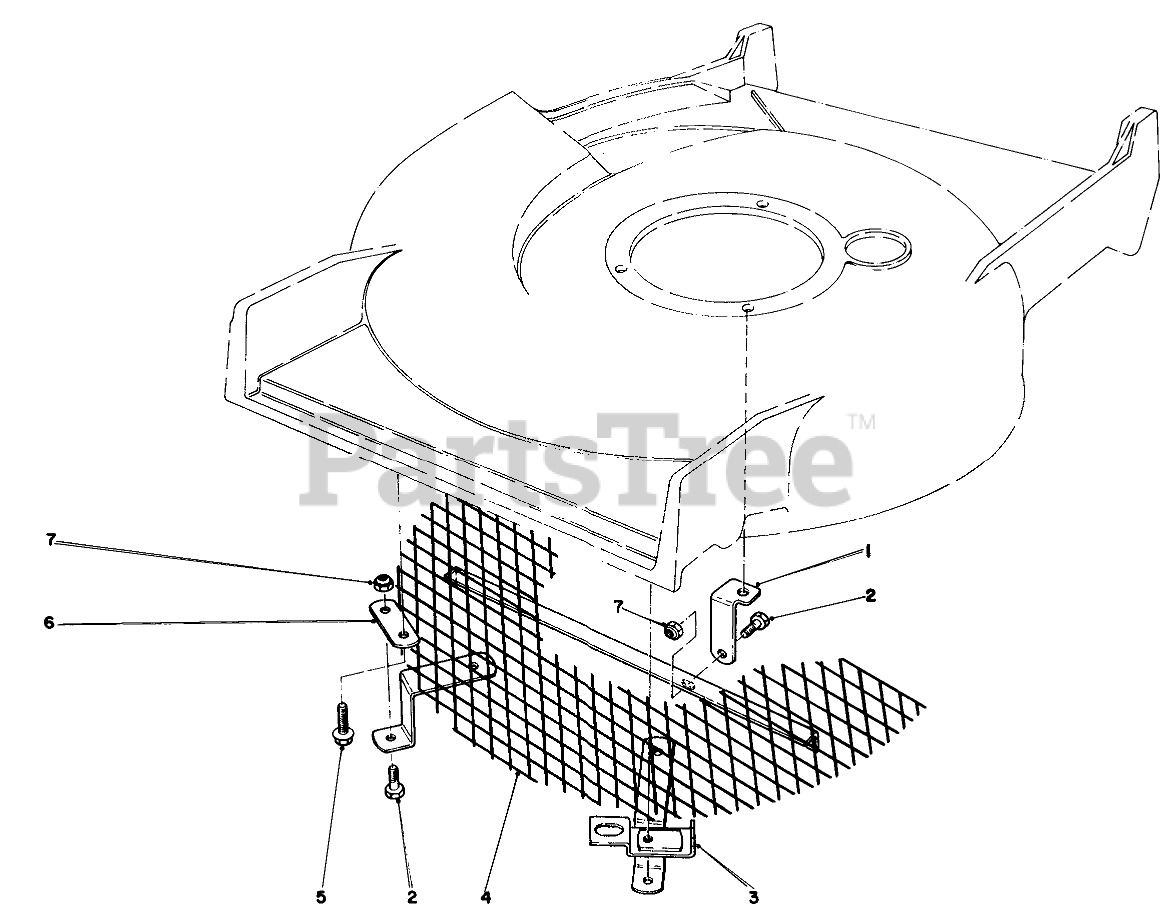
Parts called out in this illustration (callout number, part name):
1	Support Bracket
2	SCREW-HH
3	MTG. BRACKET W.A.
4	Screen
5	SCREW-HWHTF
6	ANCHOR
7	NUT-LOCK, NI
